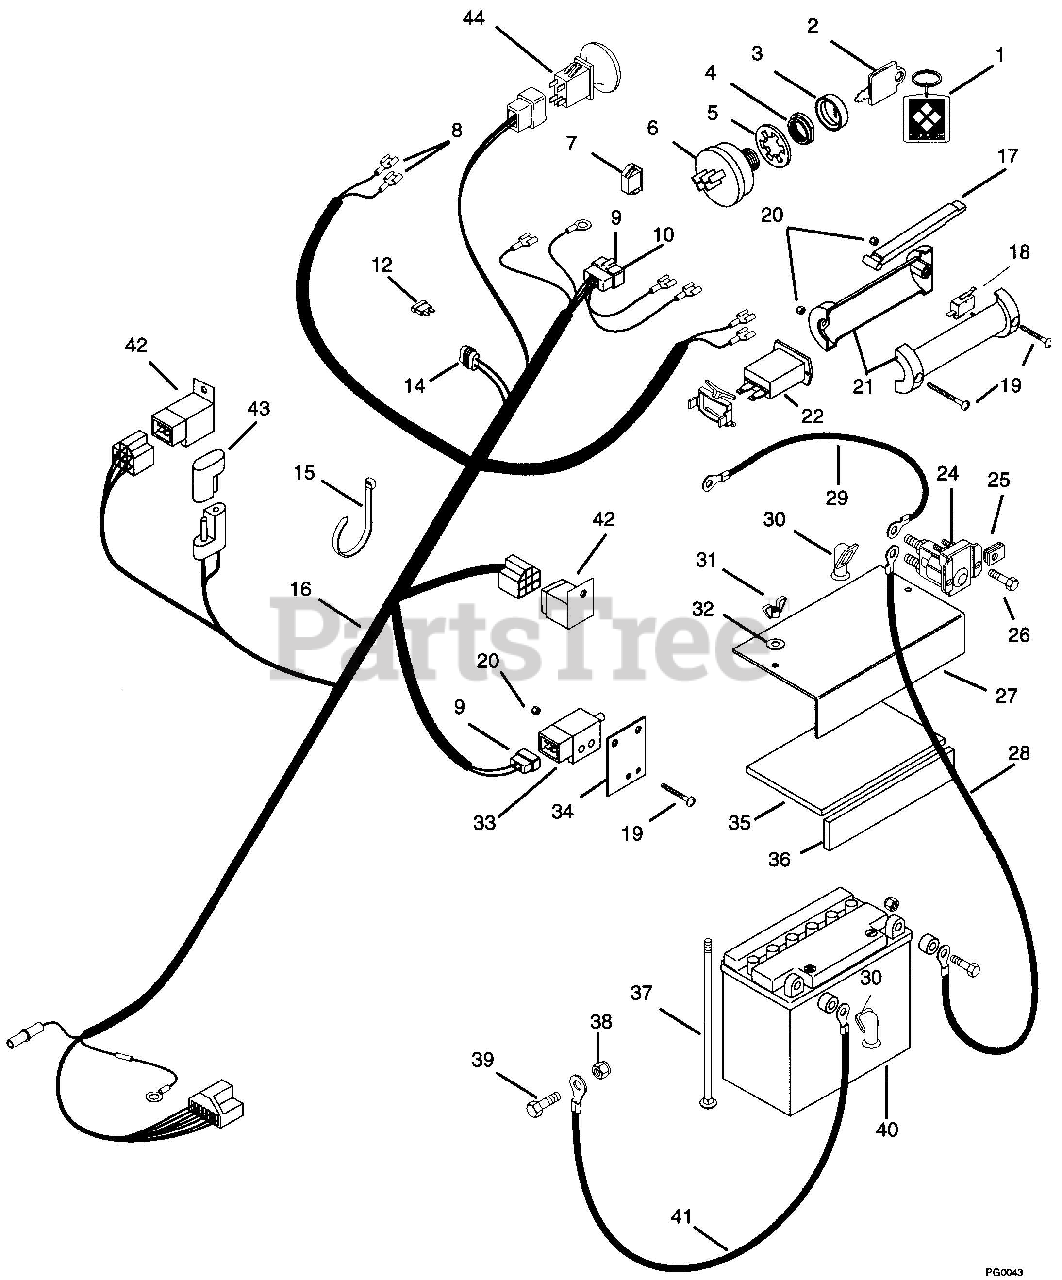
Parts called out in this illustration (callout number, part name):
1	Key Chain
2	Ignition Switch Key
3	Cap - Ignition Switch
4	Nut-Panel .625-32
5	Washer-Lock .625
6	Key Switch
7	Light - Indicator
8	Terminal - Female
9	Terminal - Female
10	Connector
12	Fuse - 30 AMP
14	Terminal - For 10-12 Guage Wire
15	Tie Wrap - Black
16	Wiring Harness Pro-300 16 B&S
16	Wiring Harness Pro-300 Kohler
17	Lever
18	Switch
19	Screw - Machine 10-24 1.50
20	Nut-Locking 10-24 Nylon
21	Handle
22	Hour Meter
24	Solenoid
25	Nut-Speed .25-20
26	Bolt-Hex .25-20 x .75 Grade 5
27	Cover - Battery
28	Cable - Battery to Solenoid
29	Cable - Starter
30	Boot - Insulator
31	Nut-Wing .250-20
32	Washer-Flat-Steel .281 x .625 x .065
33	Switch - Interlock
34	Bracket - Interlock Switch
35	Pad - Battery
36	Pad - Battery
37	Bolt-Round Head Square Neck .25-20 x 7.00
38	Nut-Locking-Center .312-18
39	Bolt-Hex .31-18 x 1.00 Grade 5
40	Battery - 12 Volt
41	Cable - Negative Battery
42	Relay
43	Molded Diode Plug - Clear 1 AMP
44	Switch - Clutch with Retainer
